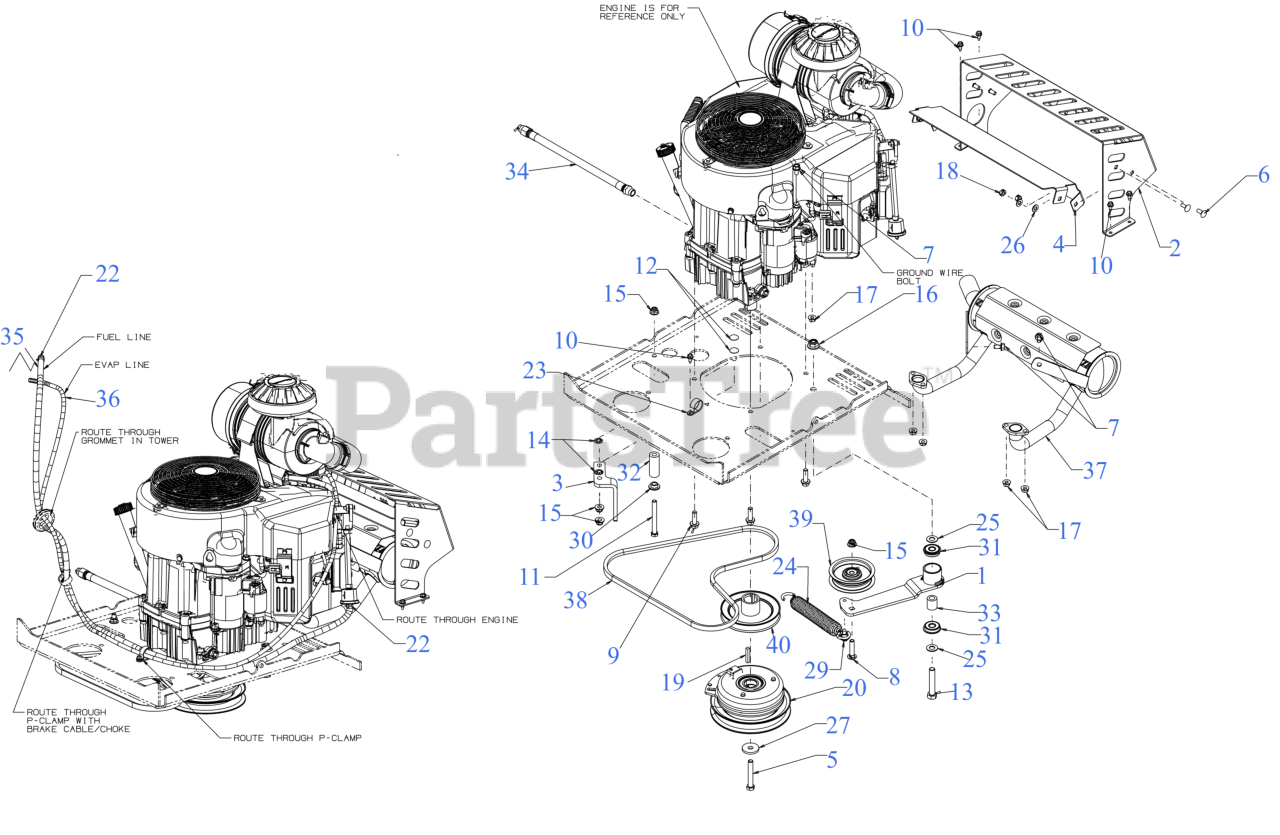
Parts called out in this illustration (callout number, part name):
1	IDLER BRACKET ASSEMBLY
2	MUFFLER SHIELD (CUB YELLOW 2)
3	CLUTCH BRACKET
4	INNER MUFFLER SHIELD
5	SCREW 7/16-20:2.75 GR5
6	CARRIAGE BOLT 5/16-18 x .75
7	SCREW M8 x 1.25 x 16MM GR8.8
8	CARRIAGE BOLT 3/8-16 x 1.75 GR5
9	SCREW 3/8-16 x 1.25 GR5
10	SCREW 1/4-20X.625
11	SCREW 3/8-16 x 3.50 GR5
12	CARRIAGE BOLT 3/8-16 x 1.00 GR5
13	SCREW 1/2-13 x 2.75 GR5
17	HEX FLANGE NUT
19	SQUARE KEY 1/4 x 1.50
20	ELECTRIC PTO CLUTCH
21	7" CABLE TIE
22	HOSE CLAMP 1/20
23	DRAIN HOSE CLAMP
24	SPRING 1.25" DIA x 8.5" LONG
25	FLAT WASHER .510 x .995
26	FLAT WASHER
27	FLAT WASHER .45 x 1.5 x .172 HT
29	SHOULDER SCREW .43X.29X5/16-18 TT
30	SHOULDER SPACER
31	ROLLER BEARING .5X1.37X.44
32	SPACER .41 x .875 x 2.19
33	SPACER 0.51 x 0.88 x 1.00
34	OIL DRAIN HOSE
35	FUEL HOSE LOW PERMEATION 54"
36	VENT HOSE 3/16 ID 70"LG
38	BELT SEC A x 51.18
39	FLAT IDLER PULLEY 3.5
40	DRIVE PUMP PULLEY
